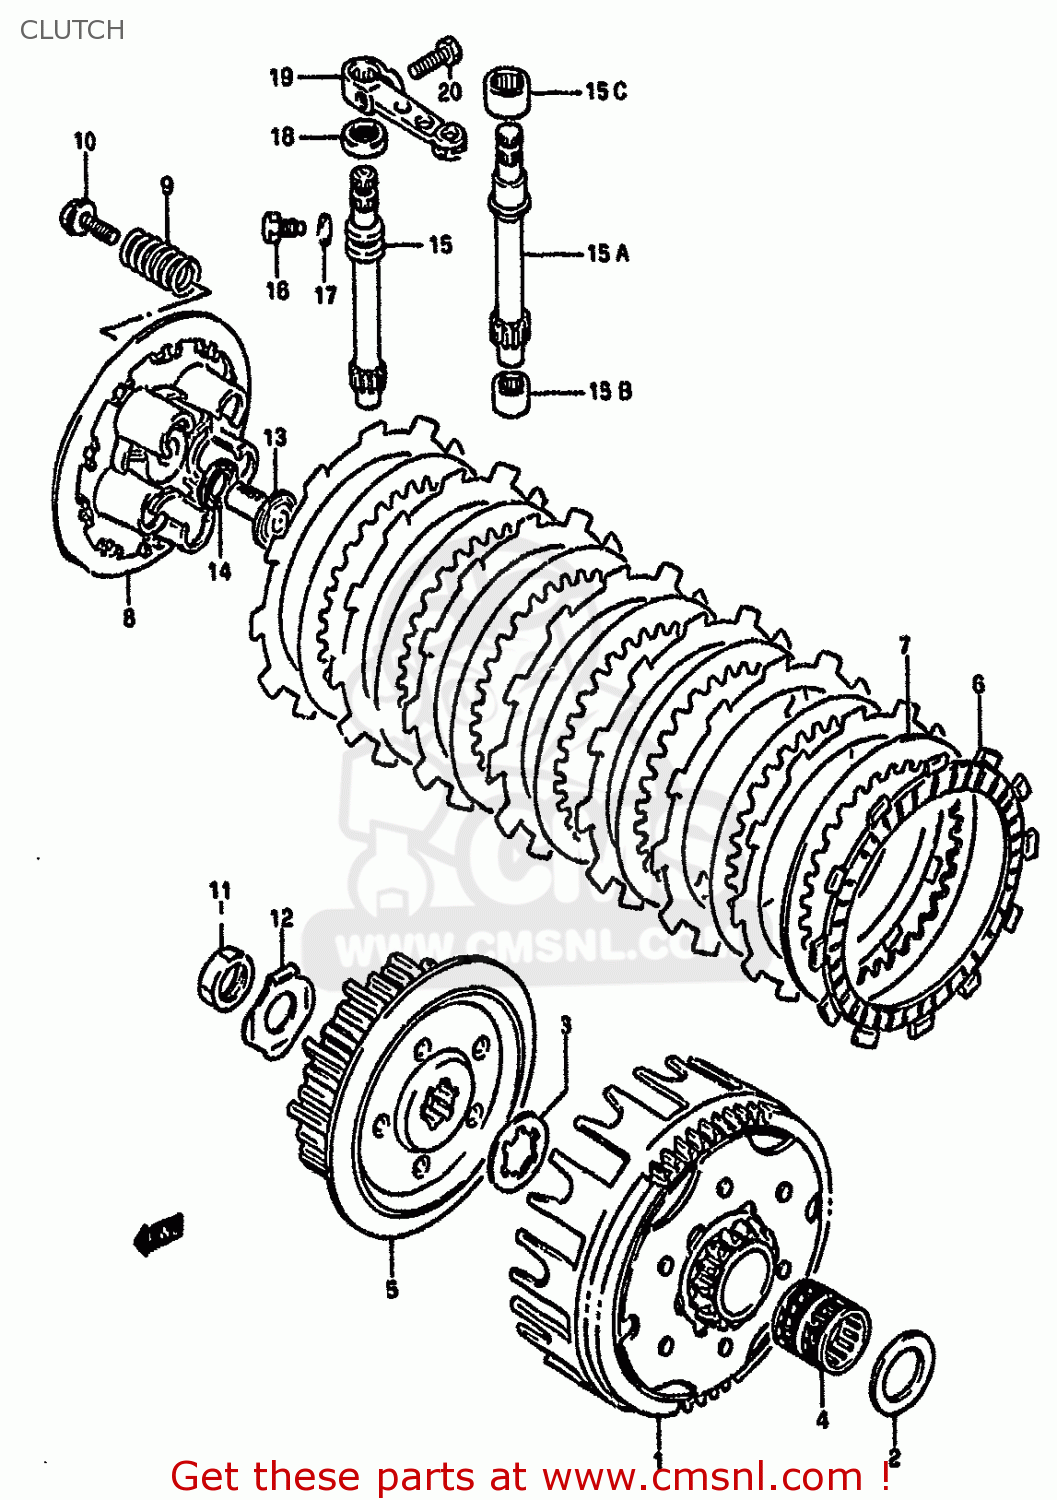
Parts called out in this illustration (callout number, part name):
1	GEAR ASSEMBLY,PRIMARY DRIVE
2	WASHER,THRUST
3	WASHER,LOCK
4	BEARING(20X25X26)
5	HUB,CLUTCH SLEEVE
6	PLATE,CLUTCH DRIVE (MCA)
7	PLATE,DRIVEN(T:1.4)
8	DISC,CLUTCH PRESSURE
9	SPRING
10	BOLT 5X16
11	NUT
12	WASHER
13	RACK,CLUTCH RELEASE
14	BEARING(10X22X2.8)
15	PINION,CLUTCH RELEASE
15A	PINION,CLUTCH RELEASE
15B	BEARING(9X13X10)
15C	BEARING(12X16X10)
16	BOLT
17	GASKET(6.2X11X1).2 (NAS)
18	SEAL,OIL(10X17X5)
19	ARM,CLUTCH RELEASE
20	BOLT
